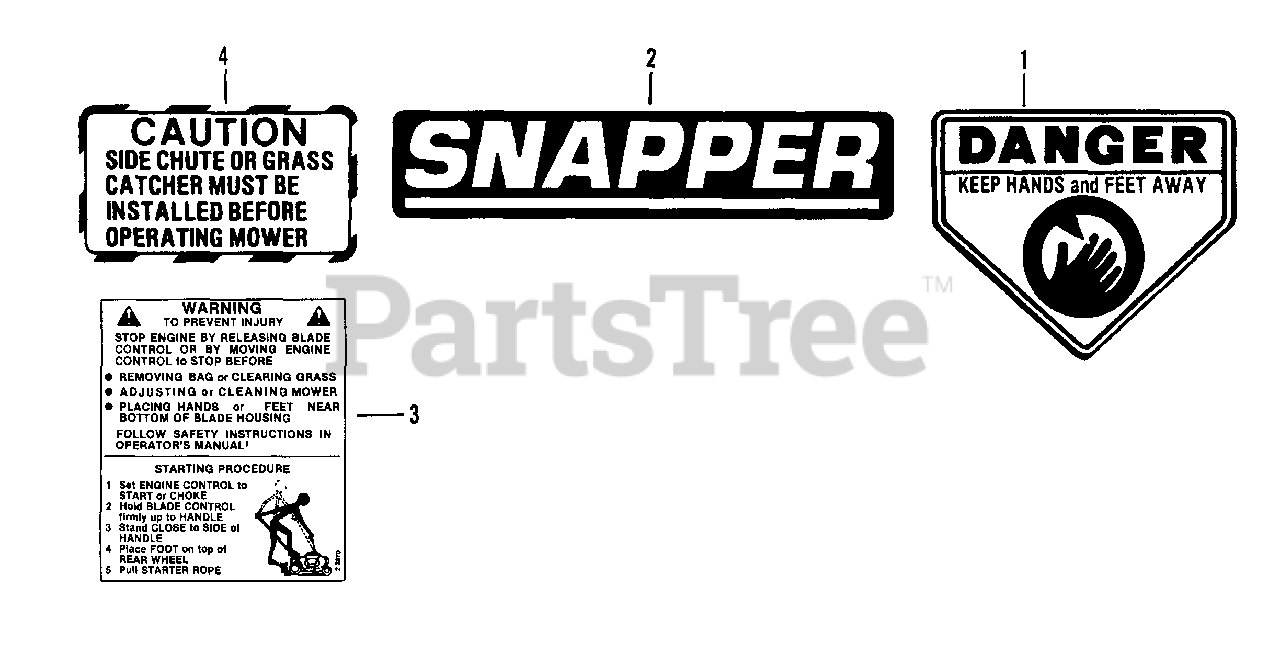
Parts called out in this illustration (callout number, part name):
1	DECAL, Danger (Keep Hands & Feet Away)
2	NAMEPLATE, SNAPPER
3	DECAL, Warning
4	DECAL, Caution
